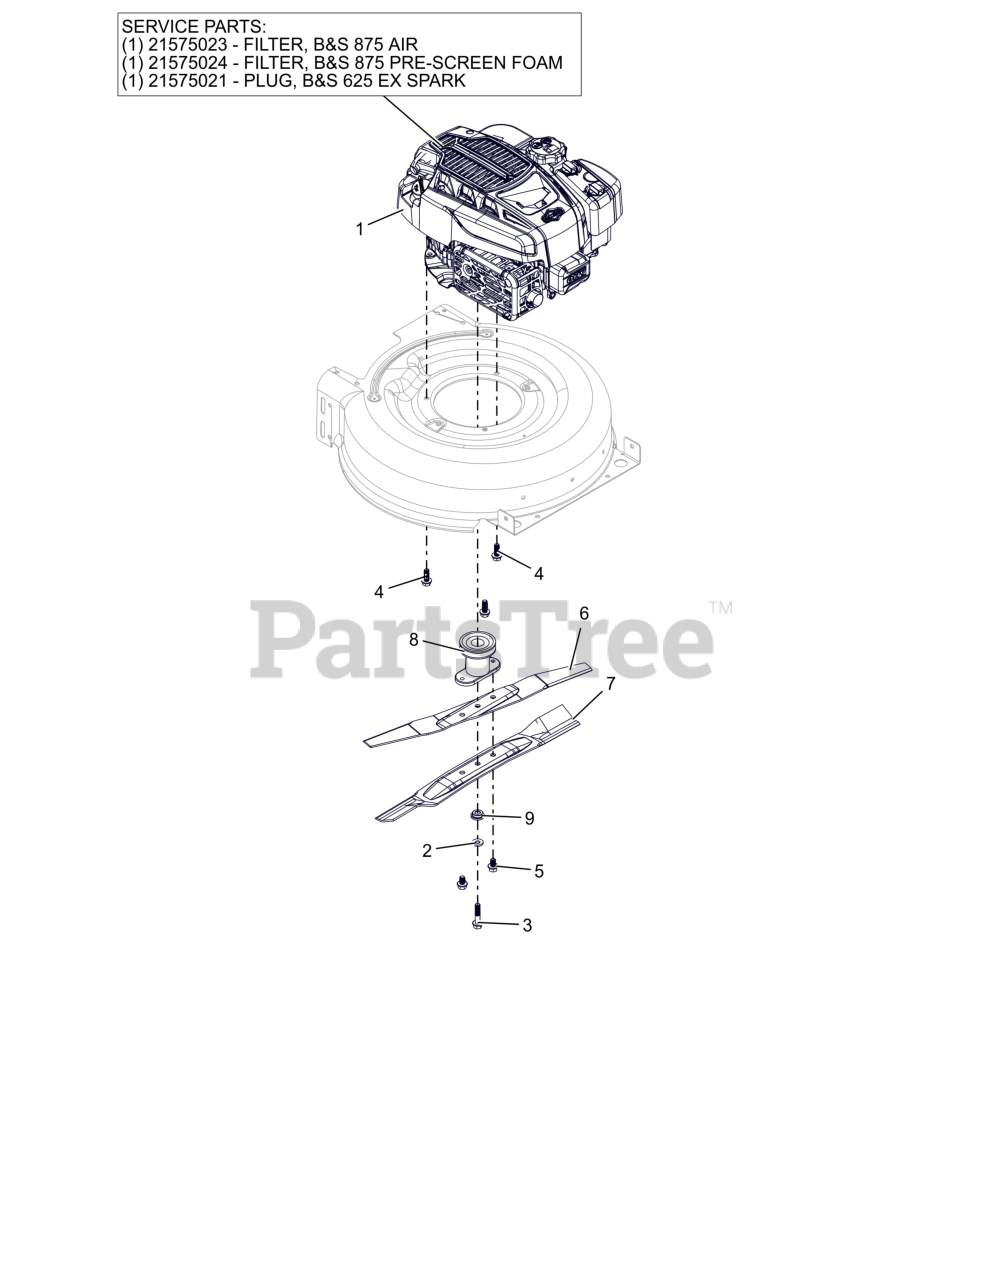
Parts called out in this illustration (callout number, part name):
1	ENGINE, BRIGGS 875 EXI MNS
1	FILTER- B&S 875 AIR
1	FILTER-B&S 875 PRE-SCREEN FOAM
1	PLUG- B&S 625 EX SPARK
2	WSHR, BLVL-.38X.875X.115
3	SCR, HEX FLANGE 3/8-24X1.75
4	SCR-TAP, 3/8-16X1.00 HWH
5	SCR, 3/8-16 x 5/8, HEX-FLG
6	BLADE- DUAL UPPER - 21"
7	BLADE, DUAL LOWER - 21
8	SPCR, BLADE - DUAL
9	SPCR, DUAL BLADE BOLT
